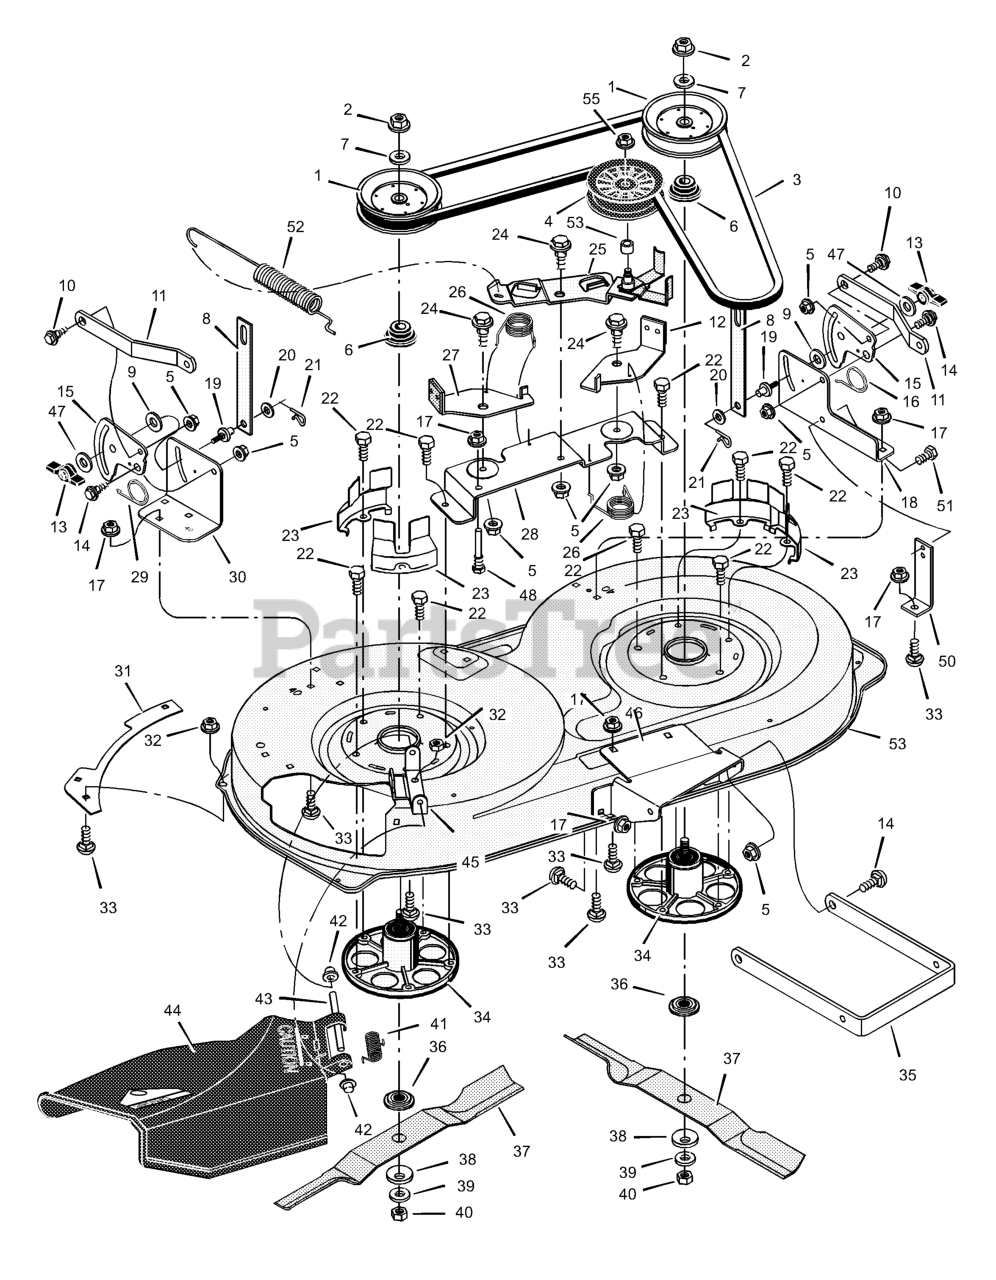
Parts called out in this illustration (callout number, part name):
1	Pulley, Jackshaft
2	Nut, Hex
3	Belt, Mower Drive
4	Pulley, Idler
5	Nut, Flange
6	Spacer, Pulley
7	Washer
8	Link, Lift
9	Pad, Friction
10	Bolt, Shoulder
11	Bracket, Suspension
12	Pad Assembly, Left Brake
13	Knob
14	Bolt, Shoulder
15	Plate, Suspension
17	Nut, Flange
18	Bracket, Suspension
19	Pin, Hanger
21	Pin, Cotter
22	Bolt
23	Cover, Pulley
24	Bolt, Shoulder
25	Arm, Idler
27	Pad Assembly, Right Brake
28	Bracket Assembly, Brake
30	Bracket, Suspension
31	Plate
32	Nut, Flange
33	Bolt, Carriage
34	Mandrell
35	Bracket, Suspension
36	Adapter, Blade
42	Cap, Push On
43	ROD, Deflector
44	Deflector Assembly
45	Bracket, Deflector
46	Bracket, Front Hanger
48	Guide, Belt
50	Bracket, Support
52	Spring, Extension
54	Housing, Blade
55	Nut, Flange
